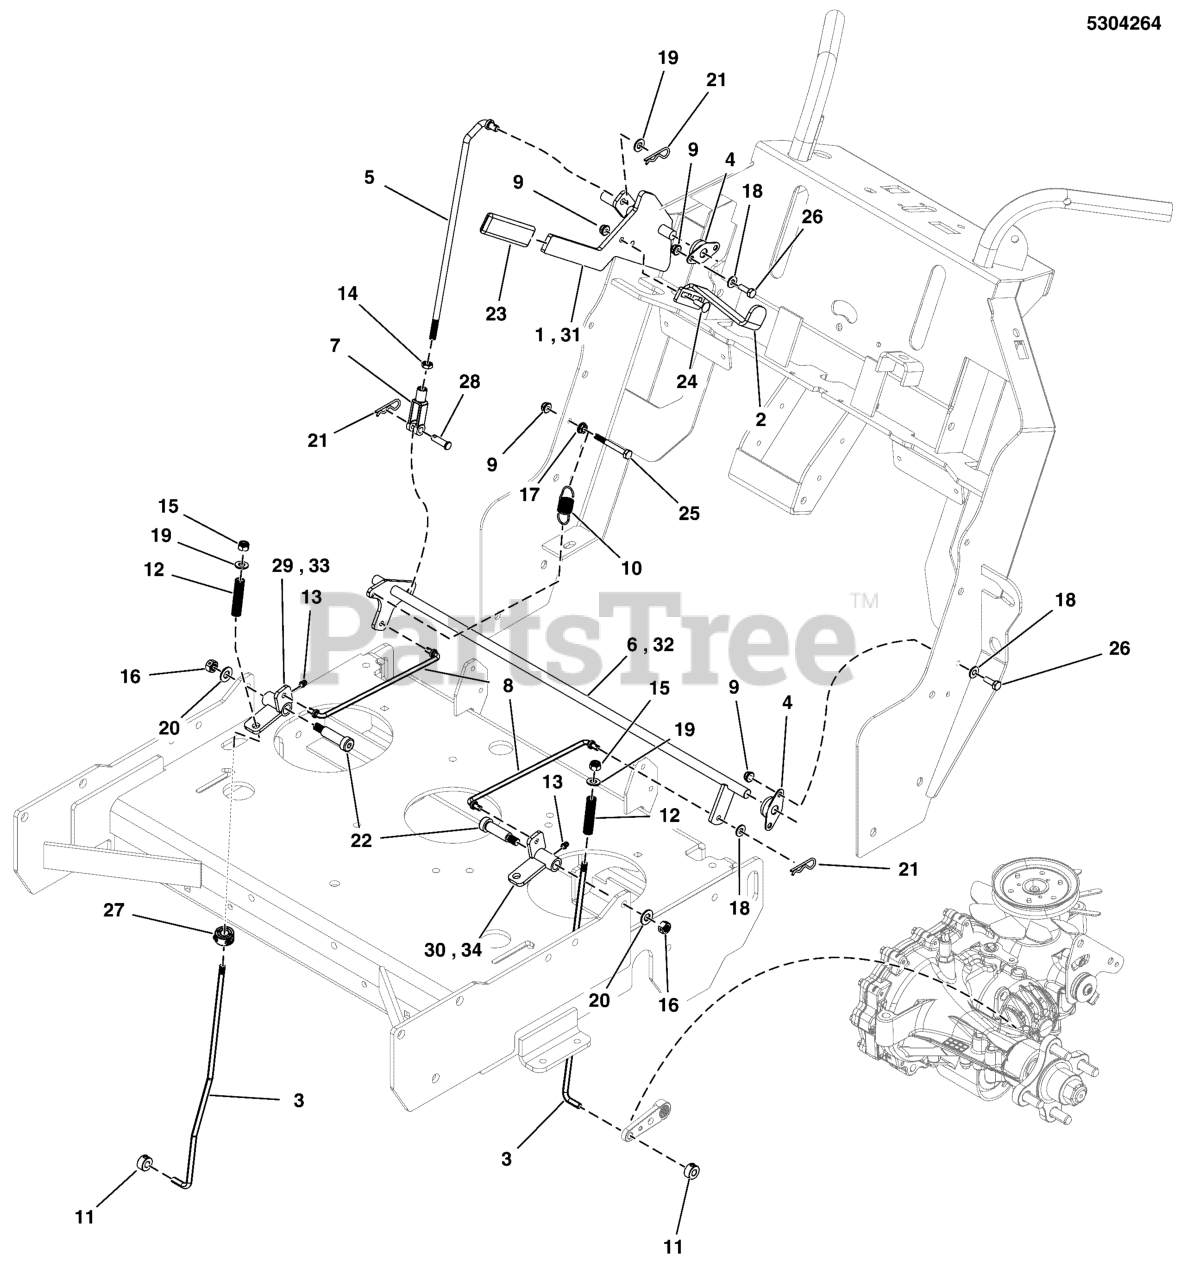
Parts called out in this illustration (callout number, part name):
1	WELD, BRAKE HANDLE, W35 - BLK
2	PLATE, NEUTRAL LOCKOUT - BLK
3	ROD, BRAKE CTRL, LOWER, SW25/FW25
4	BEARING, 1/2 FLANGED, PLASTIC BALL
5	ROD, PARKING BRAKE, W35, UPPER
6	WELD, CROSS SHAFT, W35 BRAKE - BLK
7	CLEVIS, 5/16-24, STEEL, CLEAR ZINC
8	ROD, PARKING BRAKE, W35, UPPER
9	NUT, 1/4-20 HEX NYLOCK FLANGE
10	SPRING-EXT, .740 ODX2.025LGX.072WR, BLK
11	COLLAR, 5/16 SET
12	SPRING-COMP, .375IDX2.75LGX.054WR, SS
13	GREASE FITTING, PRESS, SHORT
14	NUT, 5/16-24 JAM
15	NUT, 5/16-24 HEX NYLON LOCK
16	NUT, 3/8-16 HEX SIDE LOCK
17	NUT, 1/4-20 HEX SERR. FLANGE
18	WASHER, 1/4 SAE
19	WASHER, 5/16" SAE
20	WASHER, 3/8 SAE
21	PIN, HAIR, .0585 X 1-1/8, 1/4 EYE, CZ
22	BOLT-3/8-16 x 1-1/2, 1/2 SHOULDER
23	GRIP, FOAM, 1/4 X 1 X 4.1
24	BOLT,1/4-20X0.750,GR5,STD NECK,SQ,ZC/CL
25	BOLT, 1/4-20 X 2-1/4 GD5 CZ
26	BOLT, 1/4-20 X 3/4 GD5 CZ
27	COLLAR, DOUBLE SPLIT, 7MM
28	PIN, CLEVIS, 5/16 X 1, PLATED
29	WELD, BRAKE PIVOT, RH, W35 - BLK
30	WELD, BRAKE PIVOT, LH, W35 - BLK
31	WELD, HANDLE, W35 PARKING BRAKE - BLK
32	WELD, BRAKE ROD, W35 - BLK
33	WELD, BRAKE PIVOT, W35 - RH - BLK
34	WELD, BRAKE PIVOT, W35 - LH - BLK
